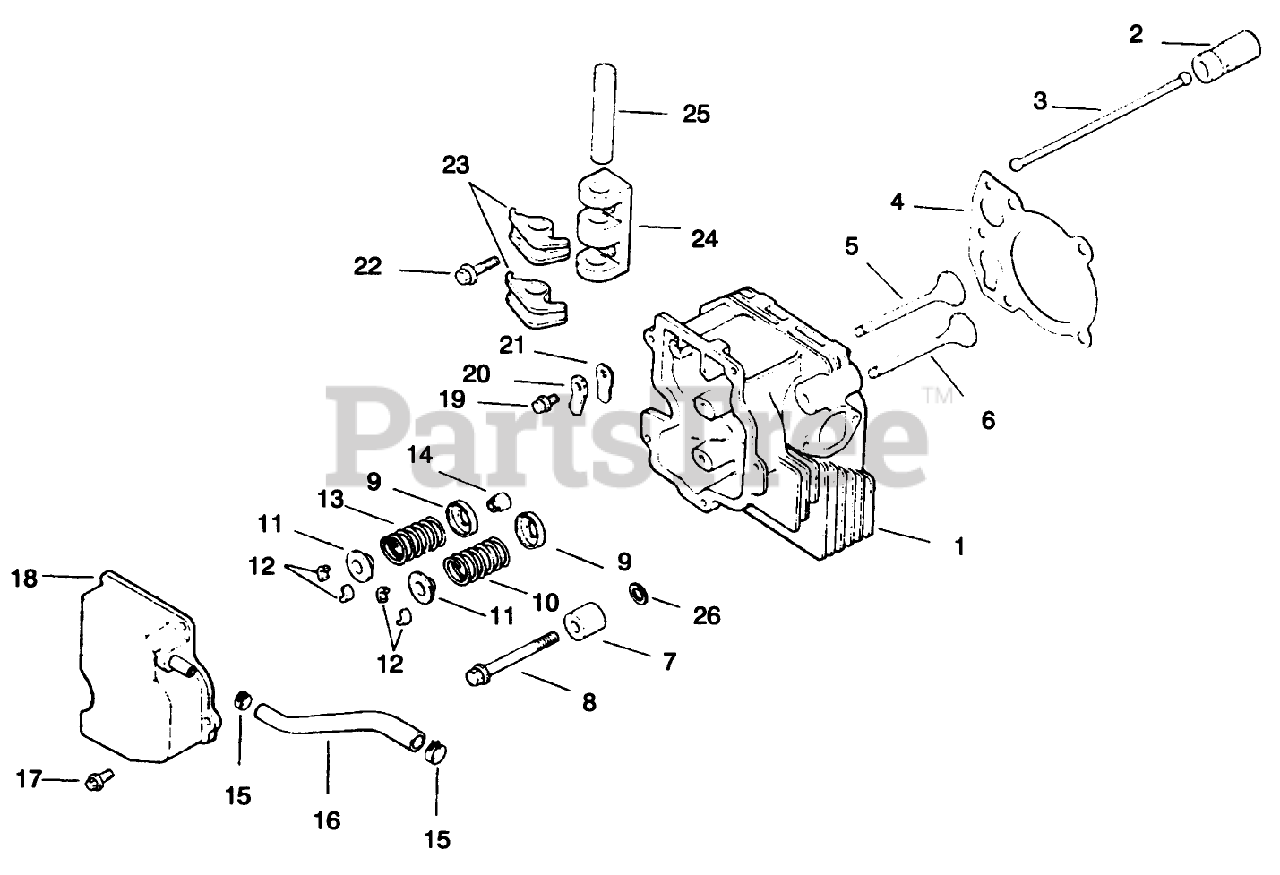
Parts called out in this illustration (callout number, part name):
1	Cylinder Head
2	Lifter-Valve
3	Rod-Push (Only On: 72042,72043,72062,72063)
4	Gasket-Cylinder Head (Only On: 72042, 72063, 72062, 72043)
5	Valve-Intake STD (Only On: 72042, 72063, 72062, 72043)
6	Valve-Exhaust STD (Only On: 72042,72043,72062,72063)
7	Spacer-Head Bolt Exhaust (Only On: 72042, 72063, 72062, 72043)
8	Screw M10x1.5x80 (Only On: 72042, 72063, 72062, 72043)
9	Retainer-Spring
10	Spring-Valve Intake (Only On: 72042, 72063, 72062, 72043)
11	Cap-Valve Spring
12	Kit-Retainer
13	Spring-Valve Exhaust (Only On: 72042,72043,72062,72063)
14	Seal
15	Clamp
16	Hose-Breather (Only On: 72042, 72063, 72062, 72043)
18	Cover-Valve W/Nipple (Only On: 72042, 72063, 72062, 72043)
20	Retainer-Reed
23	Arm-Rocker
24	Bridge-Rocker Arm
25	Shaft-Rocker Arm
26	Washer-Flat (Only On: 72042, 72063, 72062, 72043)
